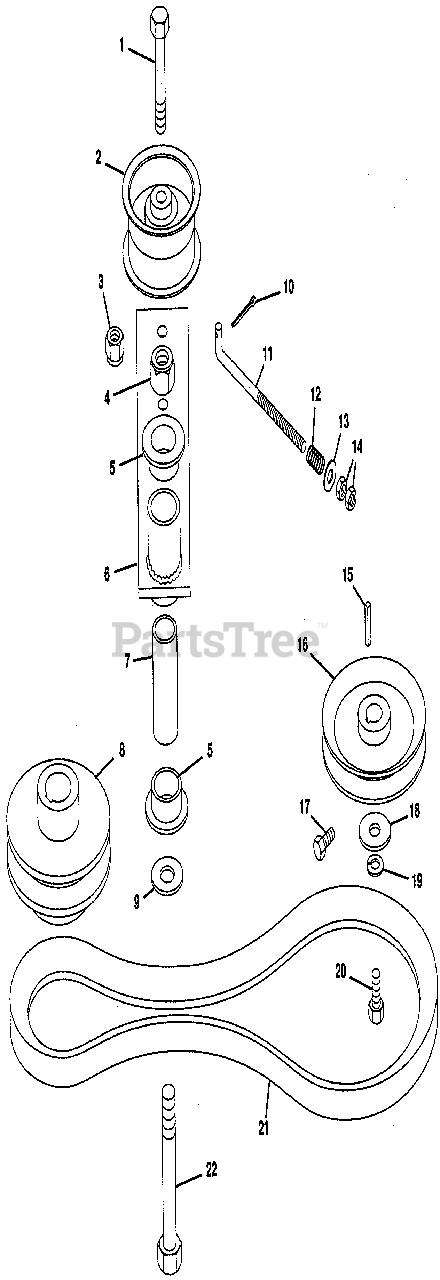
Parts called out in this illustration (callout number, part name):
1	BOLT, HEX 3/8-16 X 1.75
2	PULLEY, IDLER
3	NUT, LOCK 3/8-16
4	NUT, LOCK 1/2-13
5	BUSH., FLG. .764 X 1.47 X .560 NY.
6	WELDMENT, GROUND DRIVE IDLER
7	BUSH., ST. .560 X .745 X 2.04 STL.
8	SHEAVE, ENGINE GROUND DRIVE
9	WASHER, FLAT .531 X 1.062 X .095
10	PIN, COTTER .094 X .75
11	ROD, IDLER
12	SPRING, COMP. 1 X .78 X 388 LB/LN
13	WASHER, FLAT .406 X .812 X .065
14	NUT, HEX 3/8-24
15	KEY, 5MM SQ. X 25MM LG.
16	SHEAVE, HYDRAULIC PUMP
17	BOLT, HEX 1/4-20 X .50
18	WASHER, FLAT .265 X 1.250 X .063
19	WASHER, LOCK 1/4 REG.
20	BOLT, HEX M6 X 1.0 X 12MM LG.
21	V-BELT, ENGINE TO PUMP
22	BOLT, HEX 1/2-13 X 3.00
